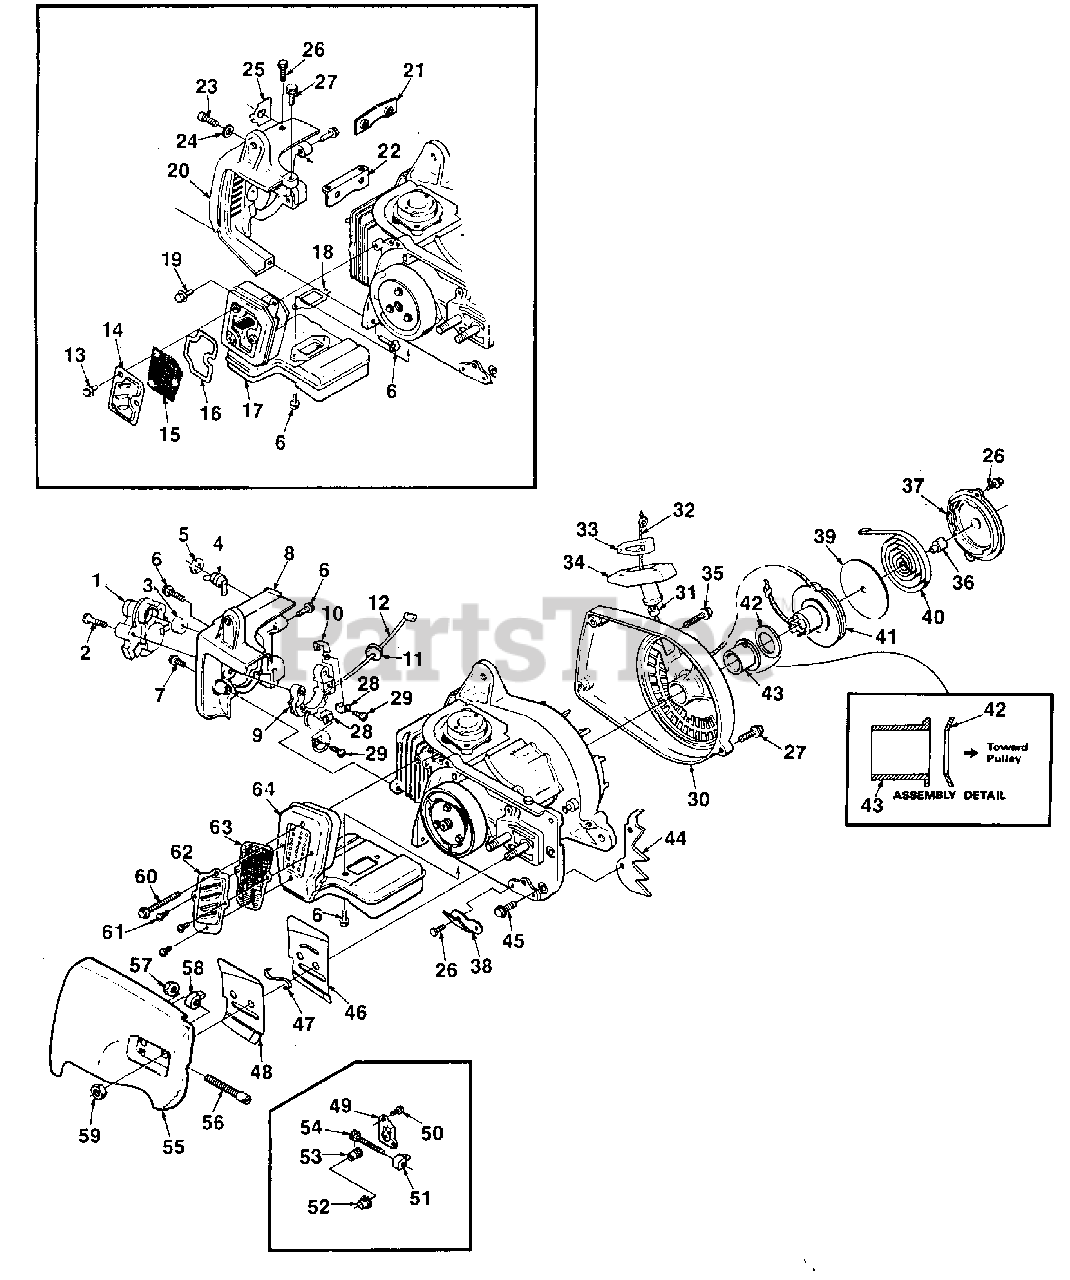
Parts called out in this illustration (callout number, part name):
1	TRANSFORMER
3	GROMMET
4	SWITCH- Grounding
5	NUT
6	SCREW- Hex sems 10-24 x 3/4
7	SCREW- 10-24 x 1 1/4 (after lot #C-320)
8	SHIELD- Cylinder (after lot #C-320)
9	RECEPTACLE- Transformer
10	CONTACT- Ground
11	GROMMET
12	LEAD- Low tension
13	SCREW- Hex sems 8-32 x 3/8 (Prior to lot #C-320)
14	PLATE- Exhaust (W) (prior to lot #C-320)
15	SPARK ARRESTOR (Accessory) (prior to lot #C-320)
16	GASKET- Exhaust plate (prior to lot #C-320)
17	MUFFLER- 360 AO (prior to lot #C-320)
18	GASKET- Muffler
19	SCREW- Hex sems 10-24 x 1/2 (prior to lot #C-320)
20	SHIELD- Cylinder (prior to lot #C-320)
21	PLATE- Nut (prior to lot #C-320)
22	BRACKET- Cylinder (prior to lot #C-320)
23	SCREW (prior to lot #C-320)
24	WASHER (prior to lot #C-320)
25	PLATE- (Run - Stop) (prior to lot #C-320)
26	SCREW- Hex hd. w/washer 8-32 x 1/2
27	SCREW- 10-24 x 1" hex sems
28	CONTACT- Transformer
29	SCREW- Plastite pan 6 x 3/8
30	HOUSING- Rewind starter
31	BUSHING- Rope
32	ROPE- Starter (38" #4)
33	INSERT- Rope retaining
34	GRIP- Starter rope
35	SCREW- Hex sems 10-24 x 1 3/8
36	LOCK- Spring
37	COVER- Starter
38	STOP- Chain
39	SPRING- Shield
40	SPRING- Rewind
41	PULLEY & CUP
42	WASHER- Spring
43	BUSHING- Starter
44	BUMPER- Spiked (accessory)
45	SCREW- Hex hd. 10-24 x 3/8
46	PLATE- Guide bar (Inner)
47	SPRING- Guide bar
48	PLATE- Guide bar (Outer)
49	COVER- Gear
50	SCREW- Pan hd. mach 6-32 x 3/8
51	PIN-Guidebar adjusting
52	BUSHING
53	ADJUSTER- Guide bar
54	SCREW-Guidebar adjusting
55	COVER- Drivecase
56	SCREW- Guide bar adjusting
57	NUT- Centerlock (10-32)
58	PIN-Guidebar adjusting
59	NUT-Hex 5/16-18
60	SCREW (After lot #C-320)
61	SCREW- (After lot #C-320)
62	PLATE- Exhaust (After lot #C-320)
63	SPARK ARRESTOR SCREEN (Opt.) (After lot #C-320)
64	MUFFLER (After lot #C-320)
